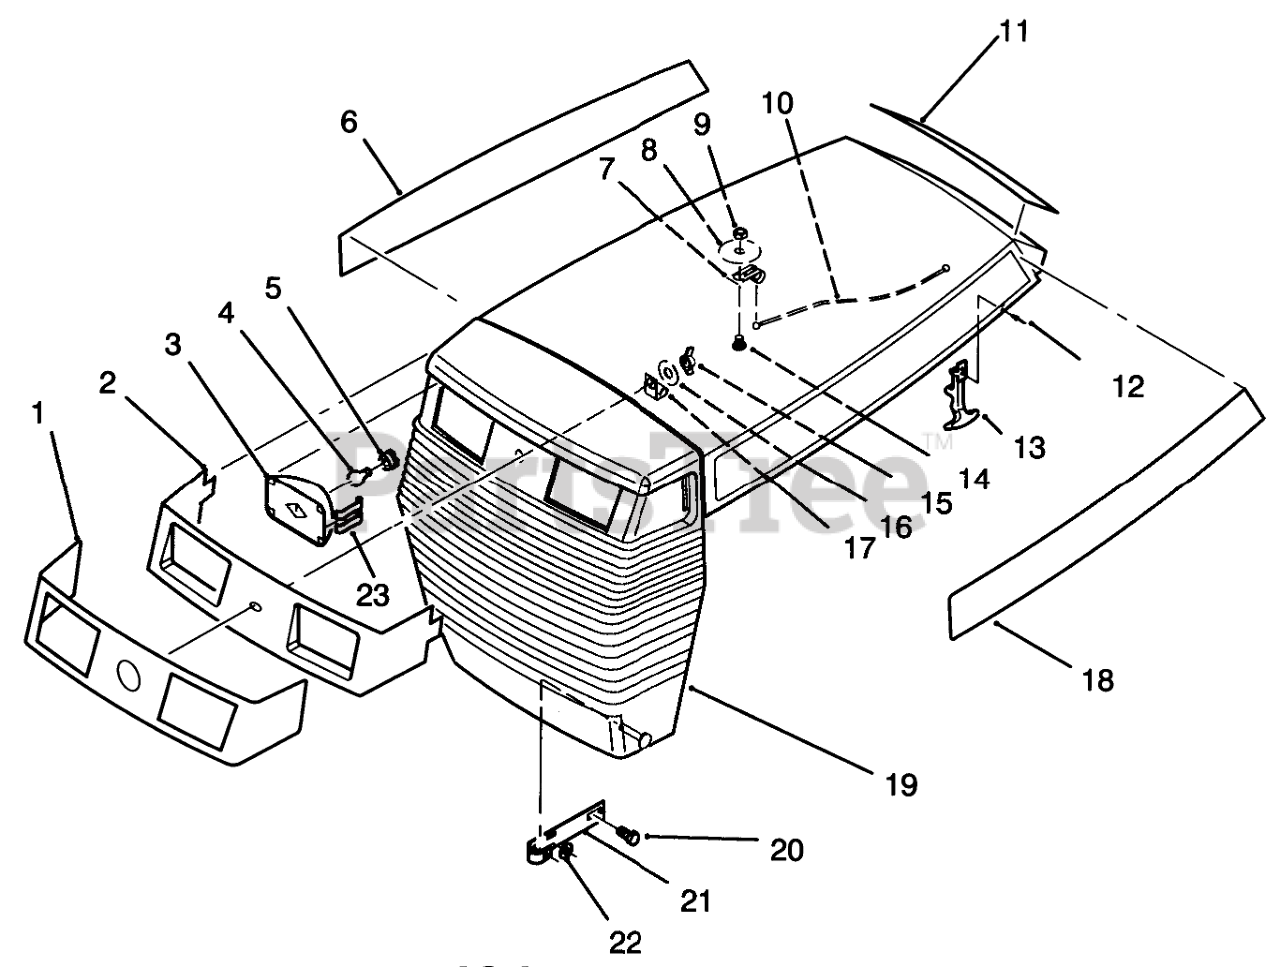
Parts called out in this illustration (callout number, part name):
1	DECAL-FRONT HOOD
2	LIGHT-BAR BLACK
3	LIGHT POD
4	BULB
5	SOCKET-HEADLIGHT
6	DECAL HOOD RH
7	CLEVIS
8	WASHER-BACKING
9	Nut
10	CABLE-ASS'Y
11	DECAL - DANGER
12	RIVET-POP
13	HANDLE ASM
14	SCREW
15	WING NUT
16	WASHER
17	J-CLIP
18	DECAL-HOOD L.H. 246H
19	Hood Assembly (Incl. Ref. #11)
20	Screw
21	BRKT-HOOD MTG L.H R
22	PUSH-NUT 5/16
23	RETAINER
